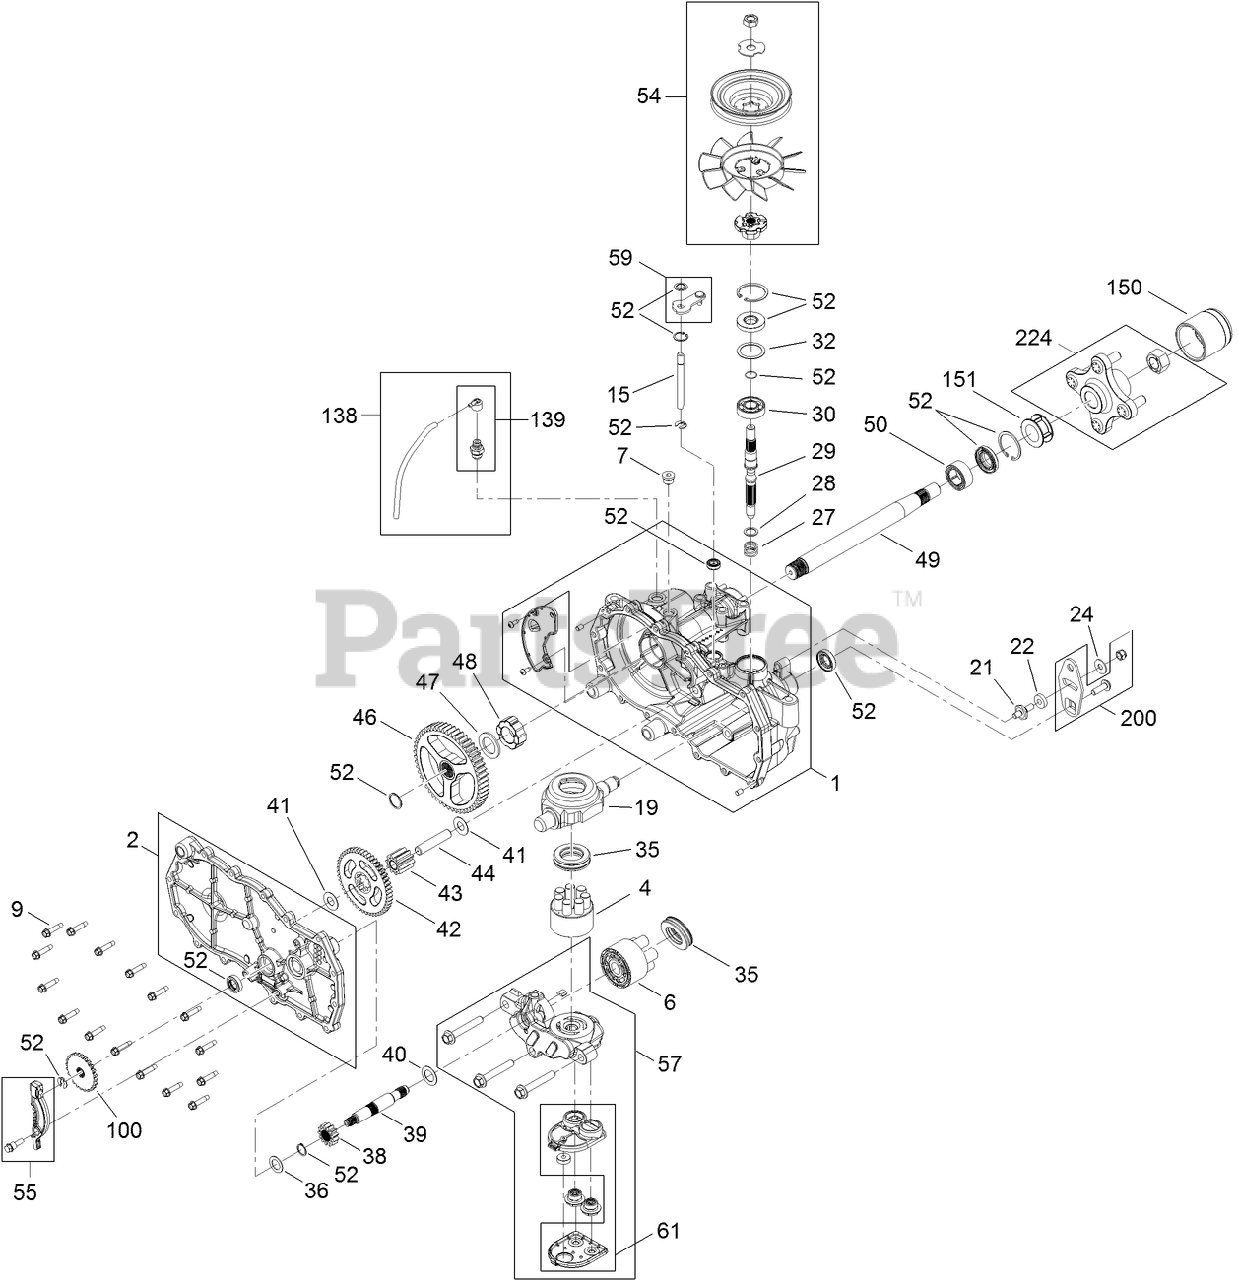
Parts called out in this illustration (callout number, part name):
1	MAIN HOUSING ASM
2	SIDE ASM
4	PUMP BLOCK ASM
6	CYLINDER BLOCK KIT
7	PLUG-THREAD, STRAIGHT
9	SCREW-HHF
15	ROD-BYPASS
19	SWASHPLATE-TRUNNION
22	PUCK-FRICTION
24	WASHER
28	WASHER
29	SHAFT-INPUT
30	BEARING-BALL
32	SPACER
35	BEARING-THRUST
36	WASHER-FLAT
38	GEAR-PINNION, 13T
39	SHAFT-MOTOR
40	WASHER
41	WASHER
42	GEAR-10T/48T
43	GEAR-JACKSHAFT, 10T
44	PIN-JACKSHAFT
46	GEAR-52T, BULL
47	WASHER
48	BEARING-SLEEVE
49	SHAFT-AXLE
50	BUSHING-AXLE
52	SEAL KIT
54	FAN PULLEY KIT
55	BRAKE ARM KIT
57	CENTER SECTION FILTER KIT
59	BYPASS ARM KIT
61	FILTER KIT
100	DISC-BRAKE, COG
138	BREATHER KIT
139	BREATHER ASM
150	CAP-AXLE, LONG
151	TUBE-AXLE
200	CONTROL ARM KIT
